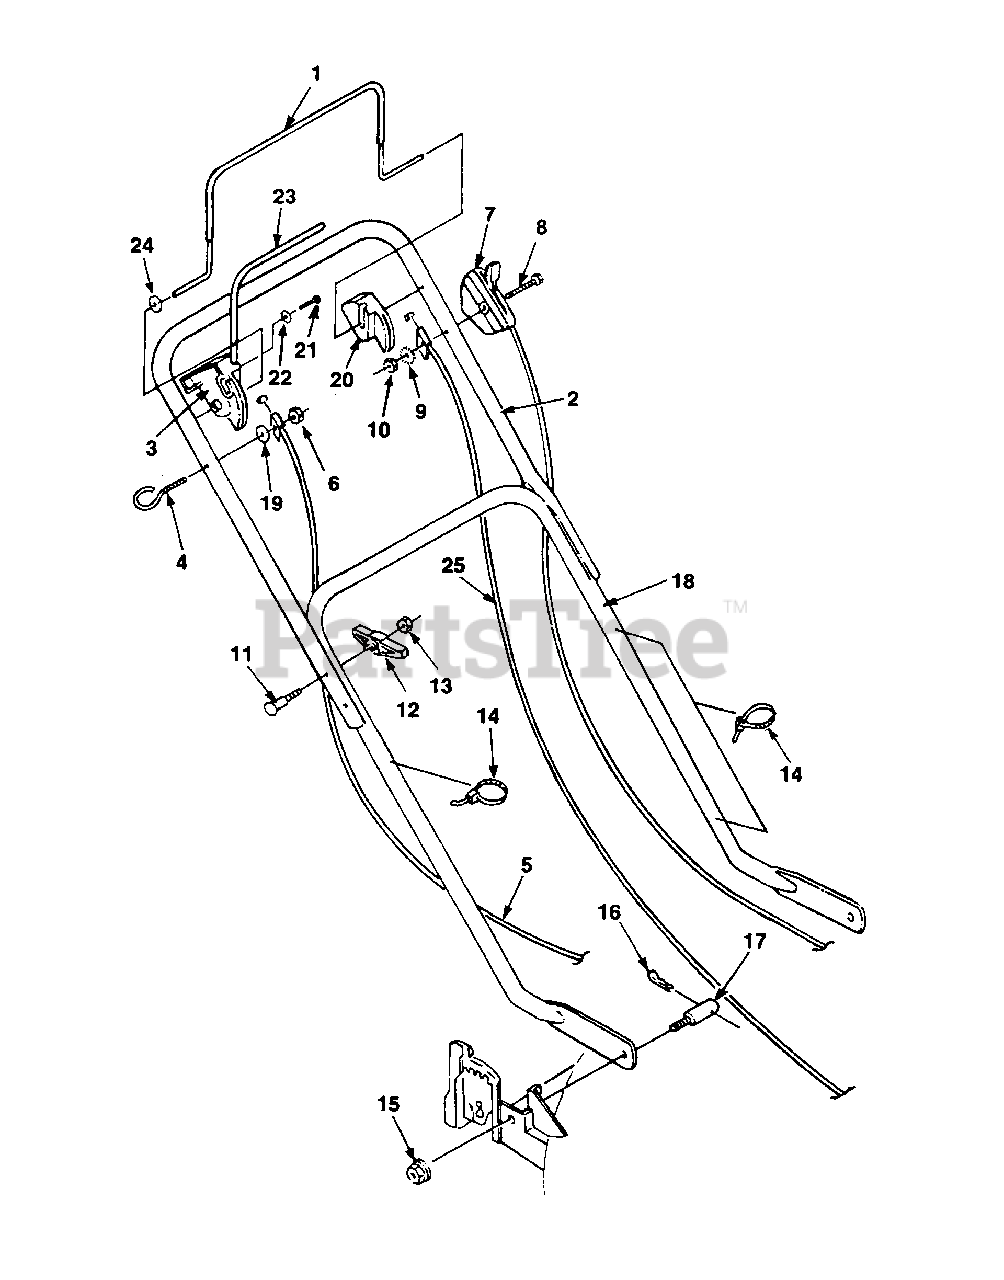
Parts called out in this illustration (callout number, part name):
1	BAIL- Brake control
2	HANDLE- Upper
4	Eyebolt - starter rope 1/4-20
6	Nut - hex 1/4-20 lock
7	CONTROL-Throttle
8	SCREW, CAP HEX HD
9	WASHER- External tooth (1/4")
10	NUT - Hex 1/4-20
12	HANDLE KNOB-TBO
13	NUT TBO
14	CABLE - Tie
15	HEX WASHER NUT-TBO
17	Stud - handle mounting
18	Handle - lower
19	WASHER
20	ACTUATOR- L.H.
21	SCREW - Hex #10-16
22	WASHER
23	TRACTION LEVER
24	FLAT WASHER(HSD'S) TBO
